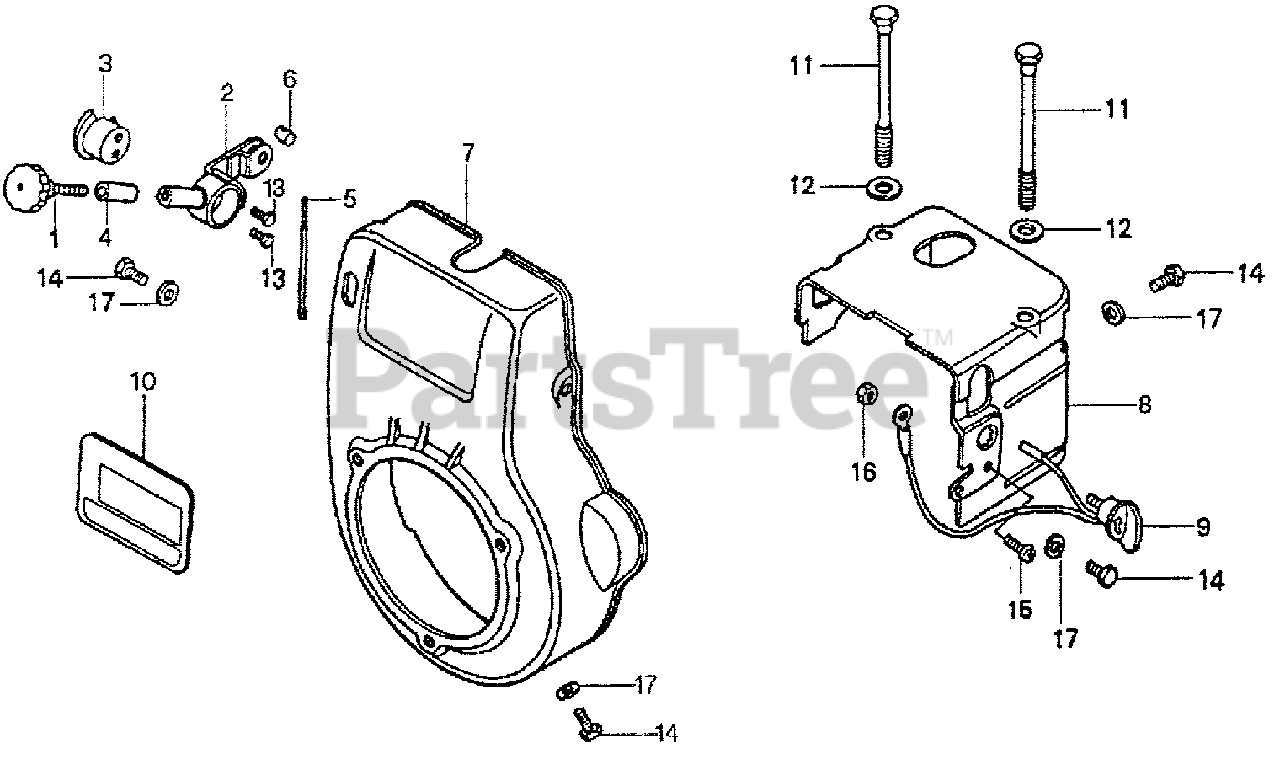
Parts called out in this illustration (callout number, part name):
1	SCREW, GOVERNOR ADJUST (NOT AVAILABLE)
2	LEVER, CONTROL (NOT AVAILABLE)
3	SHAFT, CONTROL (NOT AVAILABLE)
4	BUSH, CONTROL (NOT AVAILABLE)
5	ROD, ADJUSTING
6	JOINT, ADJUSTING ROD (NOT AVAILABLE)
7	COVER, FAN *R8* (BRIGHT RED) (NOT AVAILABLE)
8	COVER, SIDE *R8* (BRIGHT RED)
9	SWITCH ASSY., ENGINE STOP (NOT AVAILABLE)
10	PLATE, DESCRIPTION (NOT AVAILABLE)
11	BOLT, HEX. (10X76)
12	WASHER, MAGNET FIXING
13	BOLT, HEX. (5X8)
14	BOLT, HEX. (6X12)
15	SCREW, PAN (5X8)
16	NUT, HEX. (5MM)
17	WASHER, PLAIN (6MM)
